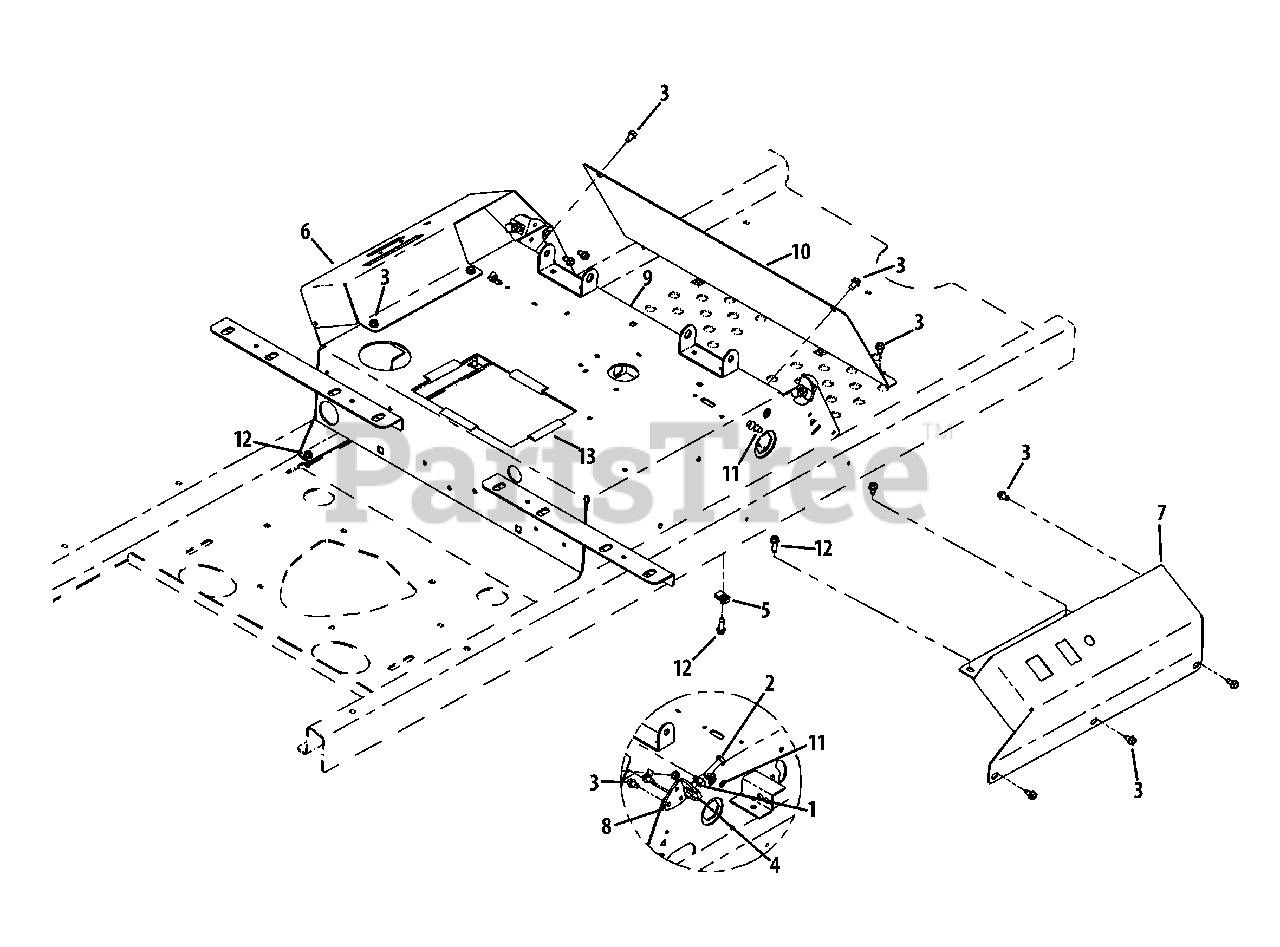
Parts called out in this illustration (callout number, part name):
1	Hex Nut, 5/16-18
2	HHCS, 5/16-18 x 1-1/4
3	Screw, 1/4-20 x 1/2
4	U-Nut, 5/16-18
5	U-Nut, 1/4-20
9	Control Housing Weldment
11	Self-Tapping Screw 5/16-18 x .750
12	Self-Tapping Screw, 1/4-20 x .75
13	Battery Edge Trim
